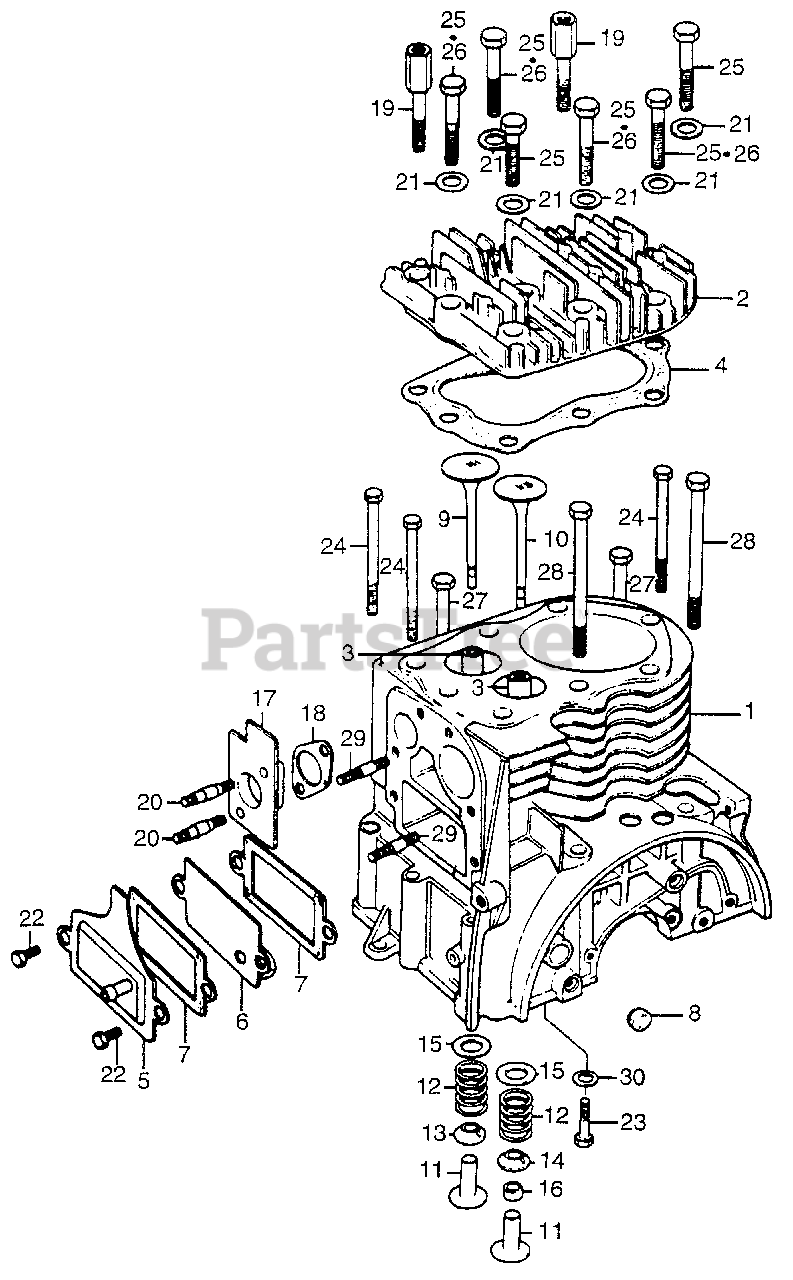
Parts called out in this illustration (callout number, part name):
2	CYLINDER HEAD
3	GUIDE, VALVE
4	GASKET, CYLINDER HEAD
5	COVER, TAPPET
16	ADJUSTER, TAPPET CLEARANCE
17	INSULATOR, CARBURETOR (NOT AVAILABLE)
18	GASKET, CARBURETOR INSULATOR (NOT AVAILABLE)
19	BOLT, CYLINDER HEAD CLAMP
20	BOLT, STUD (8X39) (NOT AVAILABLE)
21	WASHER, HEAD (8MM)
22	BOLT, HEX. (6X16)
23	BOLT, HEX. (6X32)
24	BOLT, HEX. (6X70)
25	BOLT, HEX. (8X36) (SOURCE: VINTAGE PARTS INC.)
27	BOLT, HEX. (8X70)
27	BOLT, HEX. (8X70) (NOT AVAILABLE)
28	BOLT, HEX. (8X100)
29	BOLT, STUD (6X18)
30	WASHER, PLAIN (6MM)
